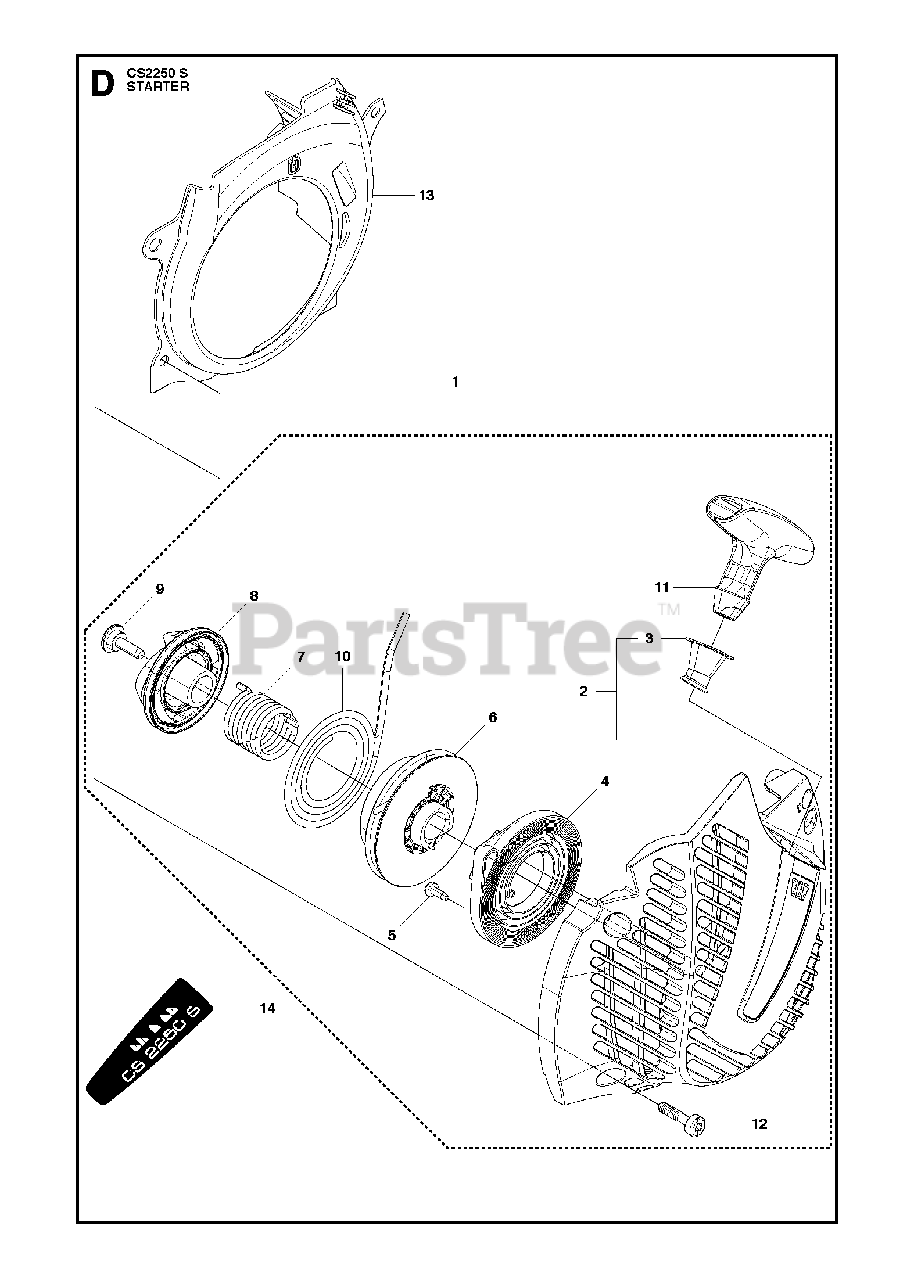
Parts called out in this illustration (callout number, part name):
1	STARTER ASSY
3	SLEEVE
4	SPRING CASSETTE ASSY
5	SCREW
6	STARTER PULLEY
7	SPRING
8	CARRIER
9	SCREW
10	STARTER ROPE
11	STARTER HANDLE
12	SCREW
13	COOLING AIR CONDUCTOR
